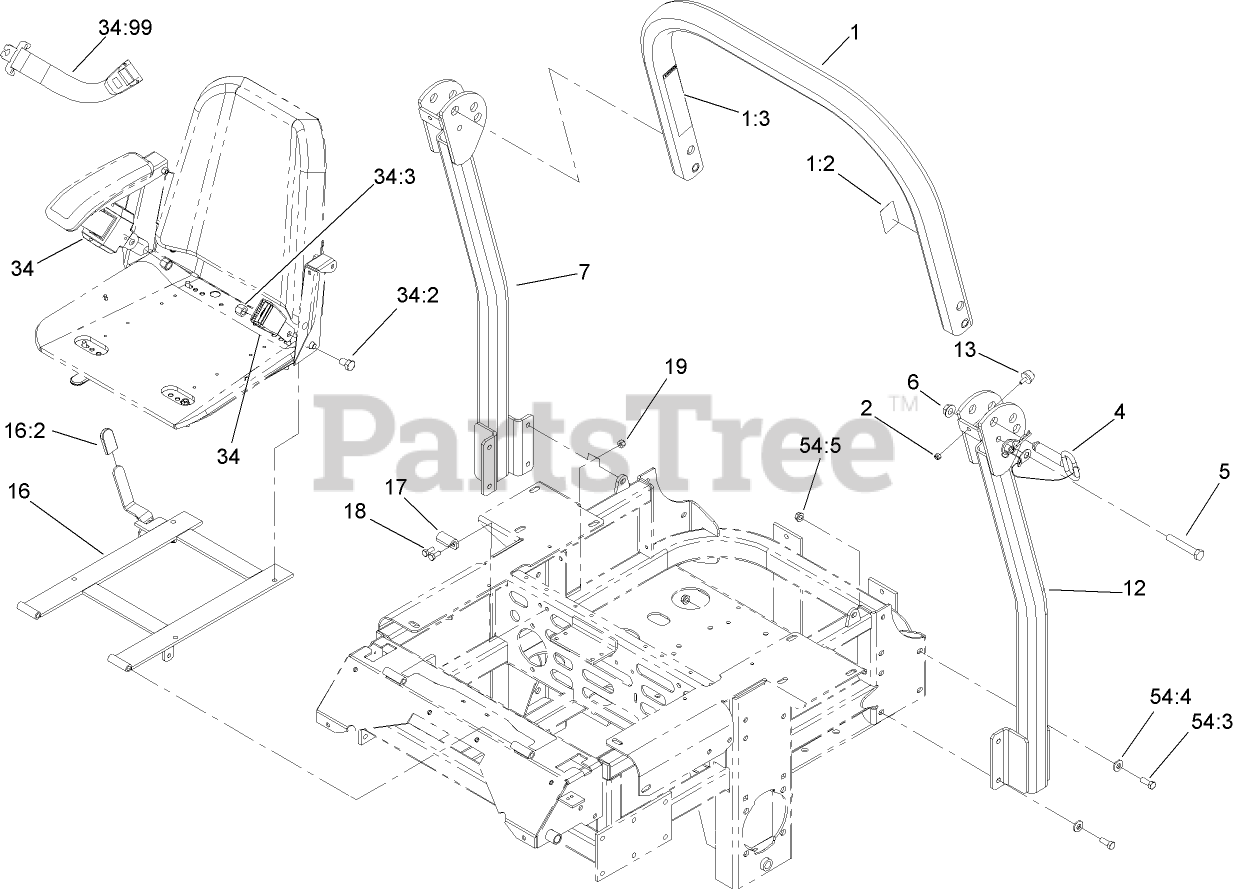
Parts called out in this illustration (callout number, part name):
1	Upper Tube ASM
1:2	DECAL-ROPS
1:3	DECAL-WARNING, FOLDING ROPS
2	NUT-LOCK, NI
4	PIN-FOLD, ROPS
5	SCREW-HH
6	NUT-HF
7	TUBE-SUPPORT, RH
12	TUBE-SUPPORT, LH
13	BUMPER-RUBBER
16	SEAT FRAME AND LATCH ASM
16:2	GRIP-LEVER
17	Catch-Latch, Seat
18	SCREW-HH
19	NUT-LOCK, NI
34	RETRACTABLE SEATBELT KIT
34:2	SCREW-HH
34:3	NUT-LOCK
34:99	SEAT BELT EXTENSION KIT
54:3	SCREW-HH
54:4	WASHER-BELLEVILLE
54:5	NUT-HHF, WHIZ
